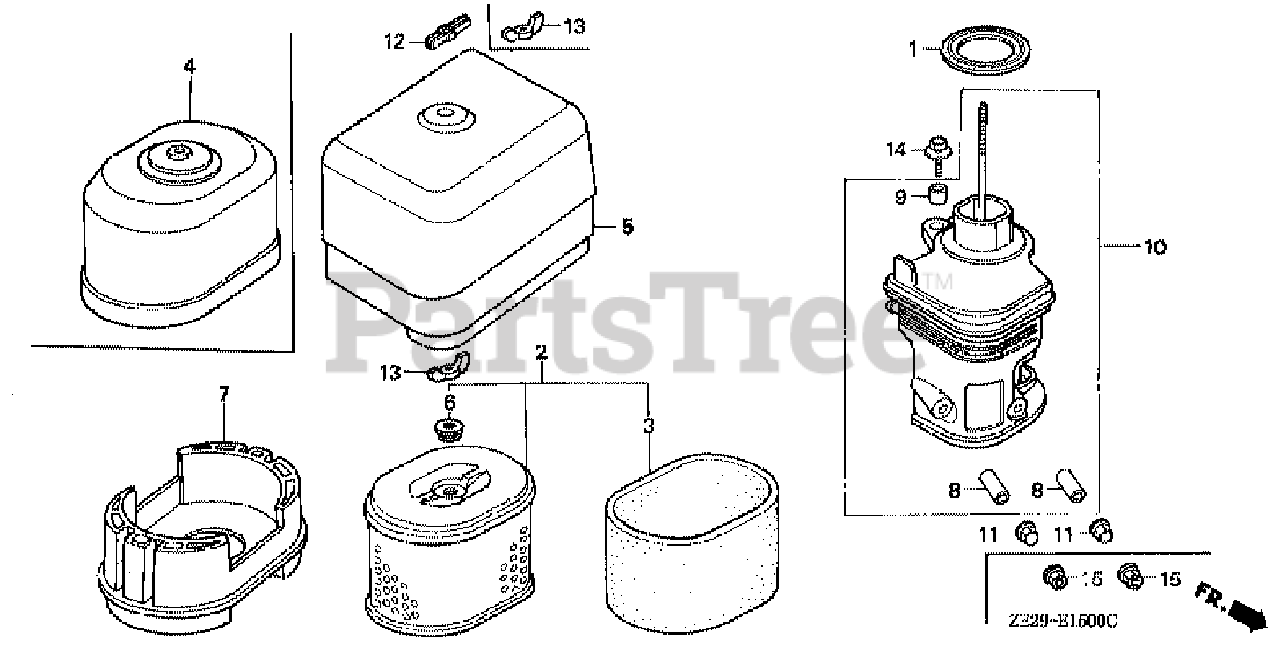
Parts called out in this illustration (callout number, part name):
1	GASKET, ELBOW
2	ELEMENT, AIR CLEANER (DUAL)
3	FILTER (OUTER)
5	COVER, AIR CLEANER
6	GROMMET, AIR CLEANER
8	COLLAR, AIR CLEANER
9	COLLAR B, AIR CLEANER
10	ELBOW, AIR CLEANER
12	WINGNUT (6MM)
13	WINGNUT, TOOL BOX SETTING
14	BOLT-WASHER (6X22)
15	NUT, FLANGE (6MM)
